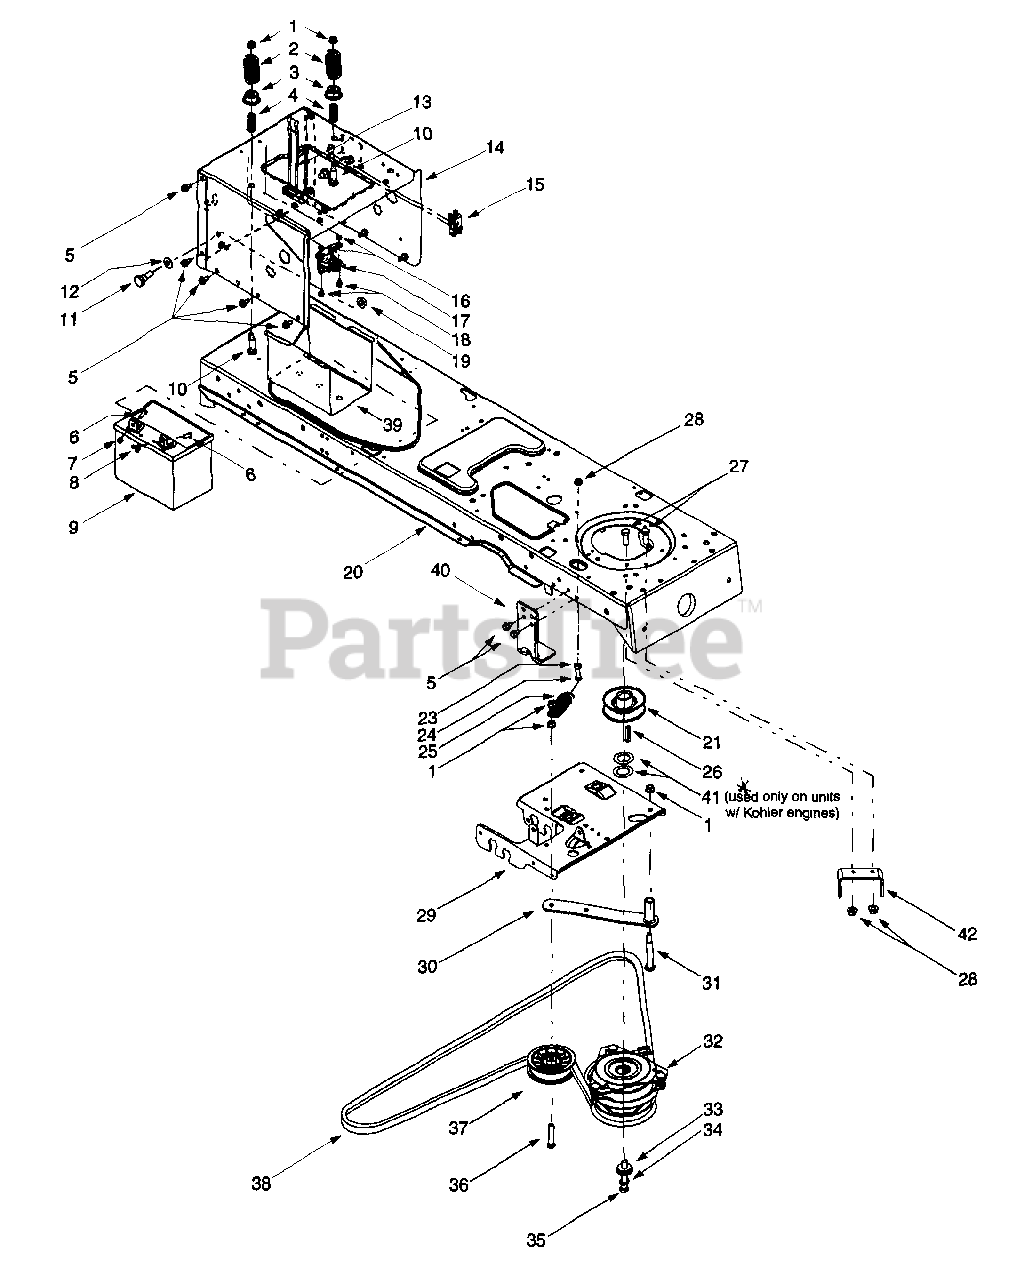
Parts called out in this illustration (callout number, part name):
1	Flange Lock Nut, 3/8-16
2	Compression Spring, 1.318 x 2.37
3	Spacer Cup, 1.5 OD
4	Compression Spring, .66 OD x 1.5
5	Self Tapping Screw, 5/16-18 x .625
6	Hex Cap Screw, 1/4-20 x .62
7	Hex Sems Nut, 1/4-20
8	Wing Nut, 1/4-20
9	12-volt Battery
10	Shoulder Screw, .5 x 1.25, 3/8-16
11	Shoulder Screw, .625 x .5, 7/16-20
12	Bell Washer, .45 x 1.0 x .062
13	Battery Strap
16	Lock Washer, 1/4
17	Solenoid, 12-Volt, 100 Amp
18	Self Tapping Screw, 1/4-20 x .5
19	Flange Lock Nut, 7/16-20
23	Hex Nut, 5/16-18
24	Hex Cap Screw, 5/16-18 x 1.75 (Grade 5)
25	Extension Spring, 1.2 OD x 3.638
26	Square Key, 1/4 x 1.5
27	Hex Cap Screw, 5/16-18 x .625
28	Flange Lock Nut, 5/16-18
30	Idler Bracket Assembly
31	Shoulder Screw, 1/2 Diameter x 2.5
32	Electric PTO Clutch
33	Shoulder Spacer, 1.38 x .445 x .36
34	Lock Washer, 7/16
35	Hex Cap Screw, 7/16-20 x 3.25 (Grade 5)
36	Hex Cap Screw, 3/8-16 x 2.25 (Grade 5)
37	Flat Idler Pulley, 3.5 OD
38	PTO Belt
